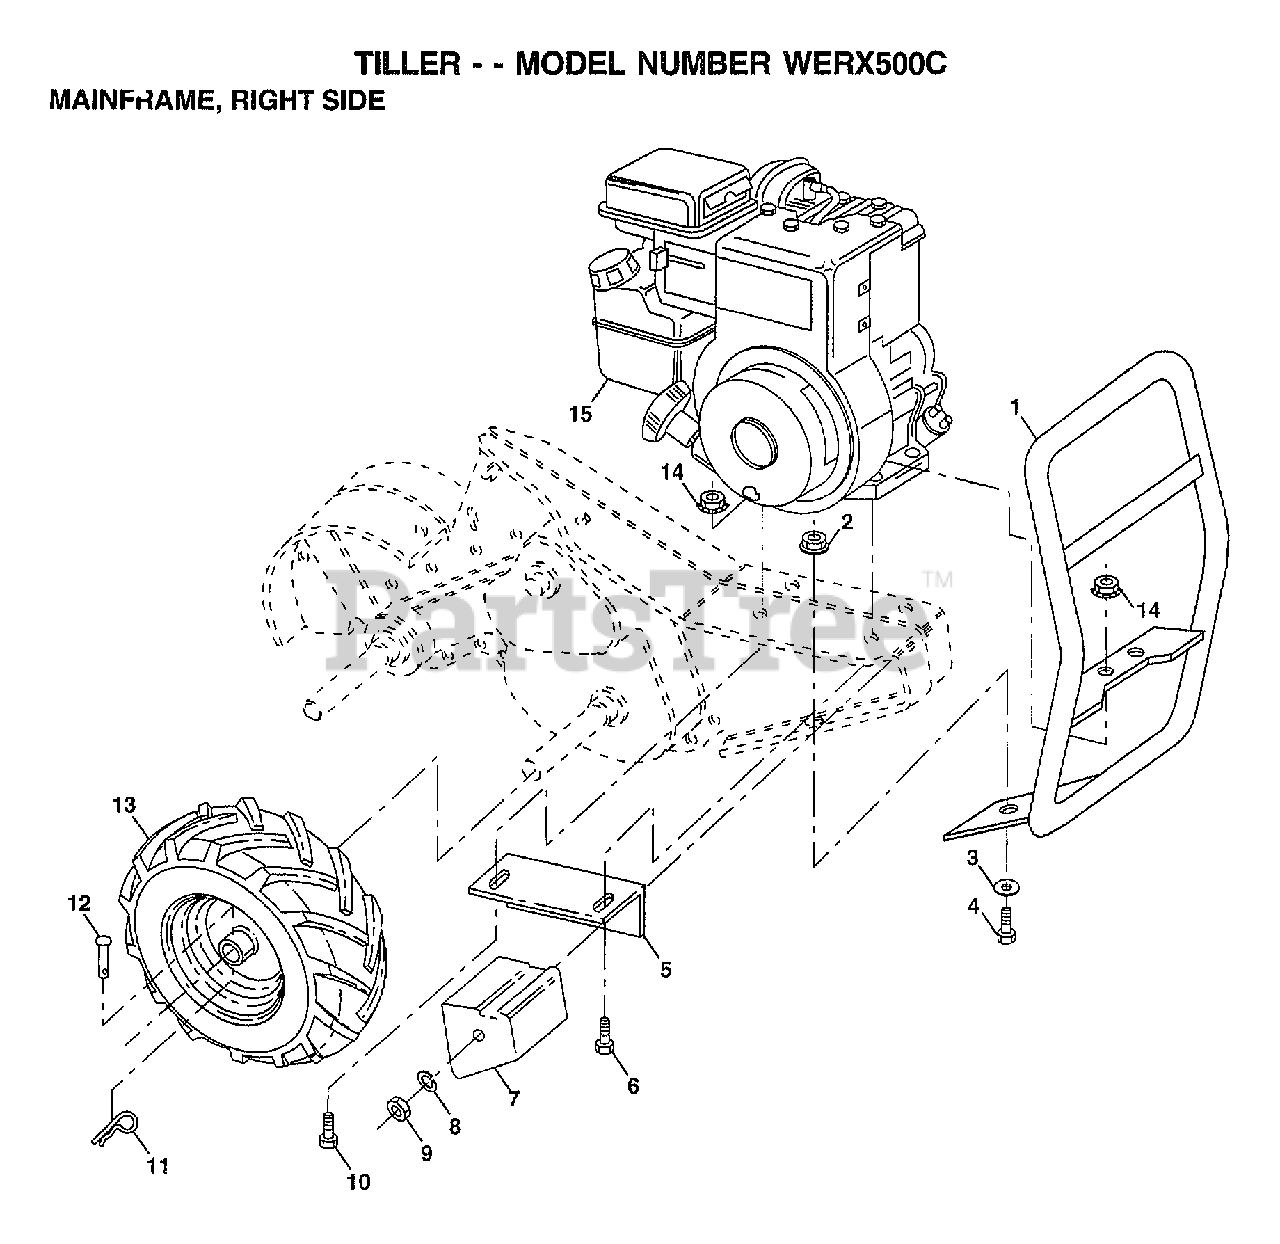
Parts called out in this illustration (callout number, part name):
1	BUMPER ASM.TILLER
2	LOCKNUT TI
3	WASHER
4	BOLT
5	BRACKET RH CRT
6	BOLT
7	COUNTERWEIGHT CRT
8	LOCKWASHER
9	NUT.HEX.3/8-16UNC
10	BOLT.HEX.5/16-1.5
11	RETAINER M
12	RIVET.DRILL.1.75
13	TIRE TI
13	RIM
